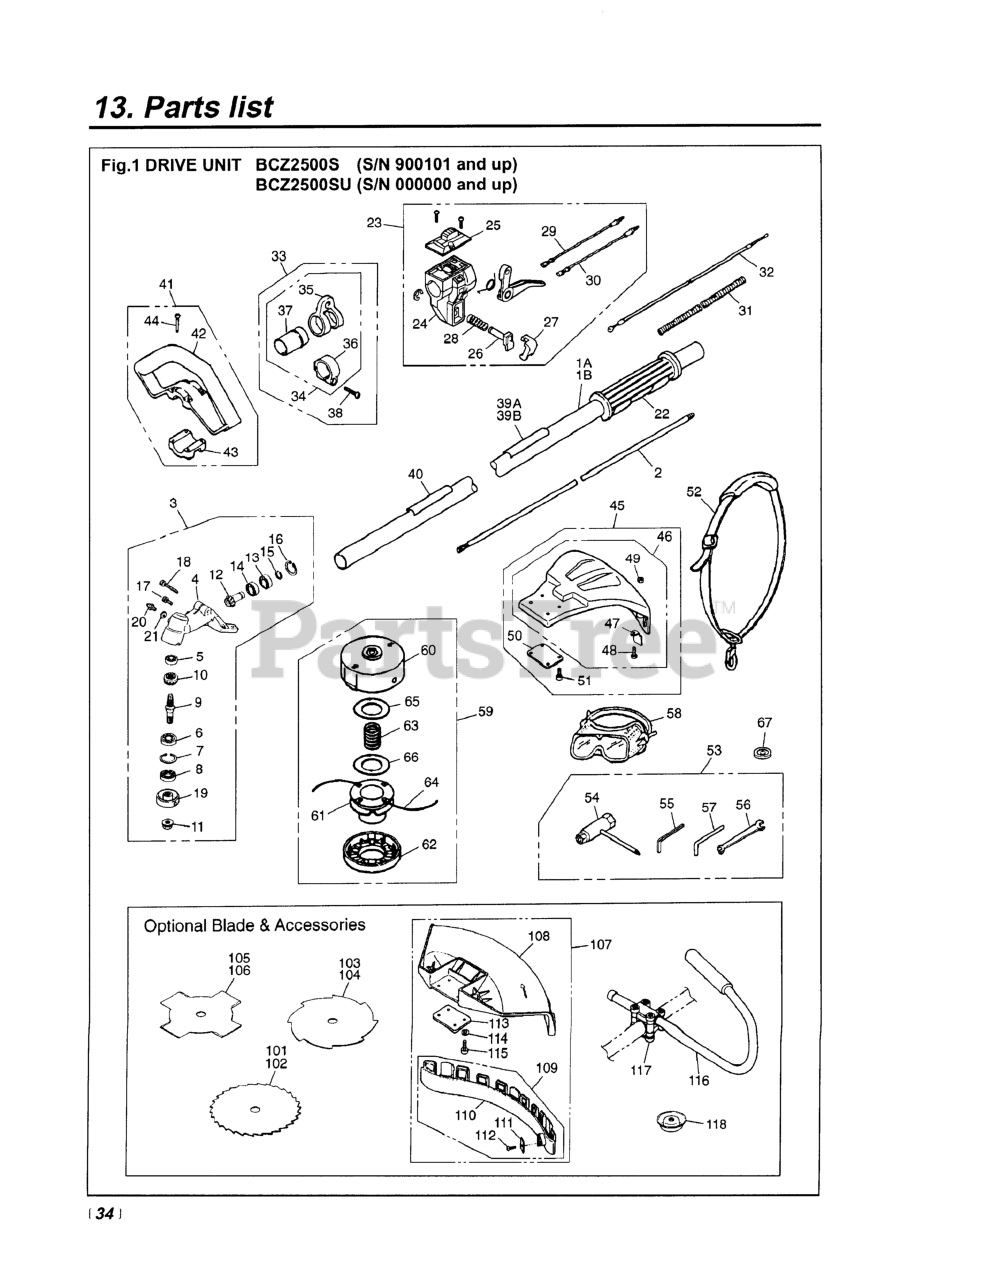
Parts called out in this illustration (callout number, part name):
1A	PIPE COMP (REPLACES -12100)
1B	PIPE COMPLETE
2	SHAFT (RPLS -12212)
3	GEARCASE ASSY (RPLS -13000)
4	GEARCASE
7	RING, SNAP, M26 X 1.2
8	SEAL, OIL
9	SHAFT
10	GEAR
11	NUT
12	PINION
16	RING, SNAP, M24 x 1.2
17	BOLT, M5 X 10
18	BOLT
19	HOLDER (A)
20	FITTING, GREASE
21	WASHER, M6 X .8
22	GRIP (RPLS 3577-32140 & 3220-
24	LEVER (USE 848-8R2-0313)
29	CORD (A), BLACK
30	CORD (B), RED
31	TUBE (RPLS 4900-72141)
32	CABLE (RPLS 5580-83100)
33	HANGER ASSEMBLY
34	HANGER COMPLETE
35	HANGER
36	CLAMP
37	SLEEVE
38	SCREW, M5 x 25
39A	NAMEPLATE
39B	NAMEPLATE
40	PLATE, CAUTION
41	HANDLE ASSEMBLY
42	HANDLE
44	SCREW, M5 x 35
45	GUARD ASSY (RPLS -24000)
46	GUARD COMP (RPLS. -24100)
47	BLADE (RPLS T3002-24120)
48	SCREW
49	NUT
50	PLATE
51	BOLT (USE 3310-31720)
52	STRAP ASSY.
54	SOCKET
55	WRENCH (TOOL)
56	SPANNER, 8 X 10 (RPLS 2540- )
57	BAR
58	GOGGLE
59	4
60	CASE (RPLS -15112)
61	HOLDER, CORD (RPLS -15141)
62	COVER (RPLS -15130)
63	SPRING (RPLS -99161)
64	CORD
65	PLATE, LARGE
66	PLATE, SMALL
67	HOLDER (B)
101	BLADE, 9
102	BLADE, 9
103	BLADE, 8
104	BLADE, 9
105	BLADE, 8
106	BLADE, 9
107	GUARD ASSEMBLY
108	GUARD
109	PLATE COMPLETE
110	PLATE
111	BLADE
113	PLATE
114	WASHER, SPRING M4 x 1.3
115	BOLT, M5 X 16
116	HANDLE, J
117	BRACKET ASSY (REPLACES -14100)
118	COVER
